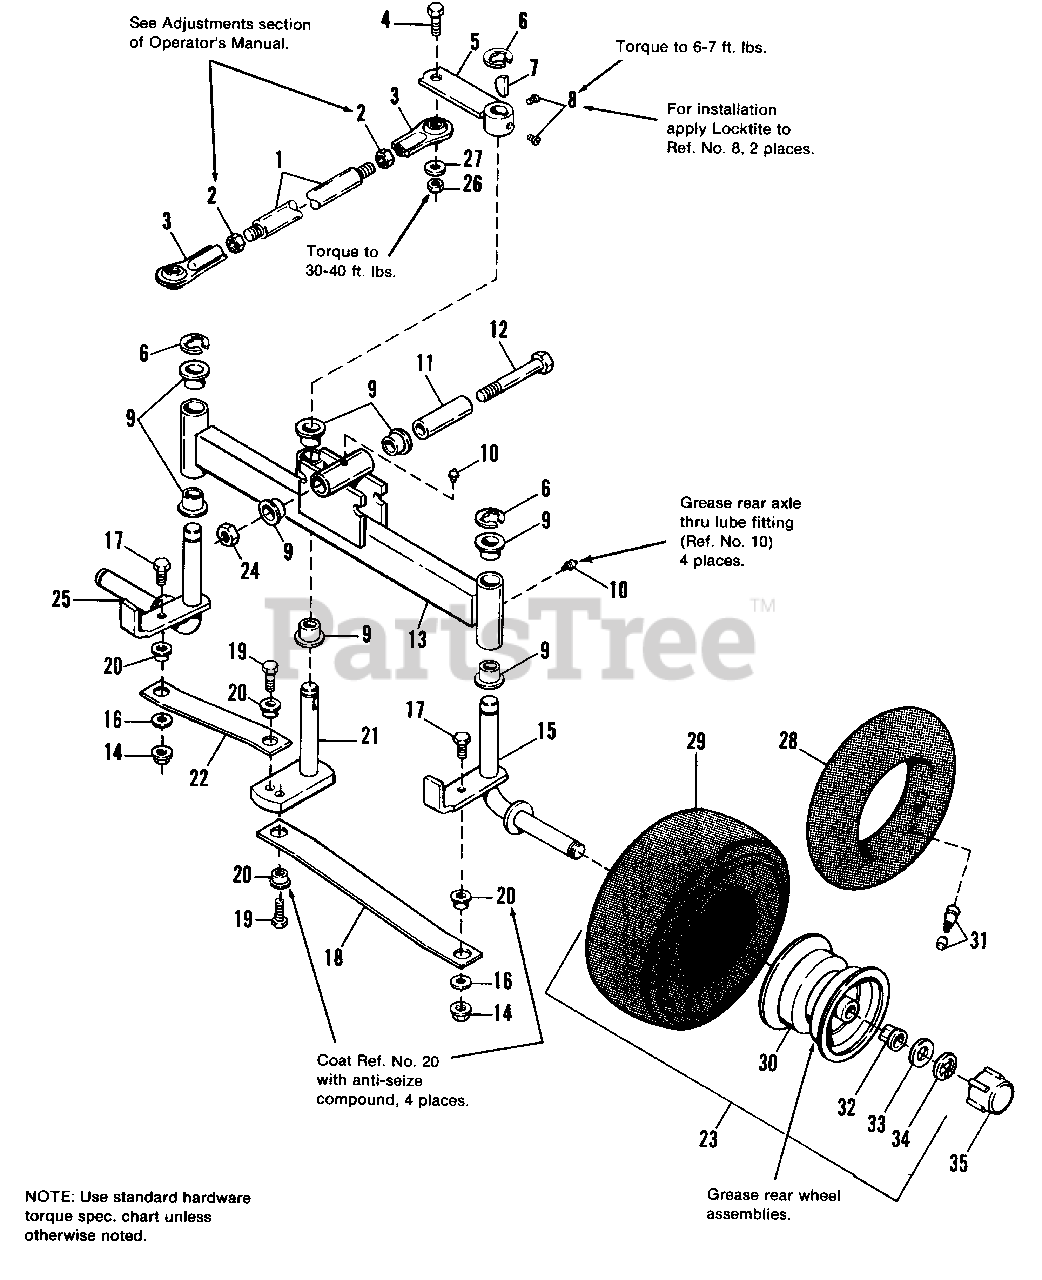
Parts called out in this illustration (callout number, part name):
2	NUT, Jam,1/2-20
3	ROD END, Ball Joint
4	CAPSCREW, Hex Hd.,1/2-13 x 1-1/2
5	STEERING ARM ASSY.
7	KEY, HiPro, 3/16 x 5/8
8	SETSCREW, Cup Pt., 1/4-20 x 5/16
9	BEARING, Nylon
10	LUBE FITTING
11	TUBE, Pivot Support
12	CAPSCREW, 1/2-13 X 4
13	REAR AXLE ASSY.
14	NUT, Centerlock, 3/8-16
15	SPINDLE ASSY., L.H.
16	WASHER, 3/8
17	CAPSCREW, Hex, 3/8-16 x 1-1/4
18	ROD, Tie
19	CAPSCREW, Whizlock, 3/8-16 X 7/8
21	STEERING ARM ASSY
23	WHEEL & TIRE ASSY., White (13 x 5.00-8)
23	WHEEL & TIRE ASSY., Silver (13 x 5.00-8)
24	NUT, Esna, Lock, 1/2-13
25	SPINDLE ASSY., R.H.
26	NUT, Esna, Lock, 1/2-13 (Thin)
27	WASHER, 1/2
28	TUBE (Service only, see note below)
29	TIRE, 13X5.00-6
30	WHEEL ASSY., White (13 x 5.00-6)
30	WHEEL ASSY., Silver (13 x 5.00-6)
31	VALVE STEM & CAP
32	BEARING
33	WASHER, 3/4
34	RING, Retaining
35	CAP, Threaded
